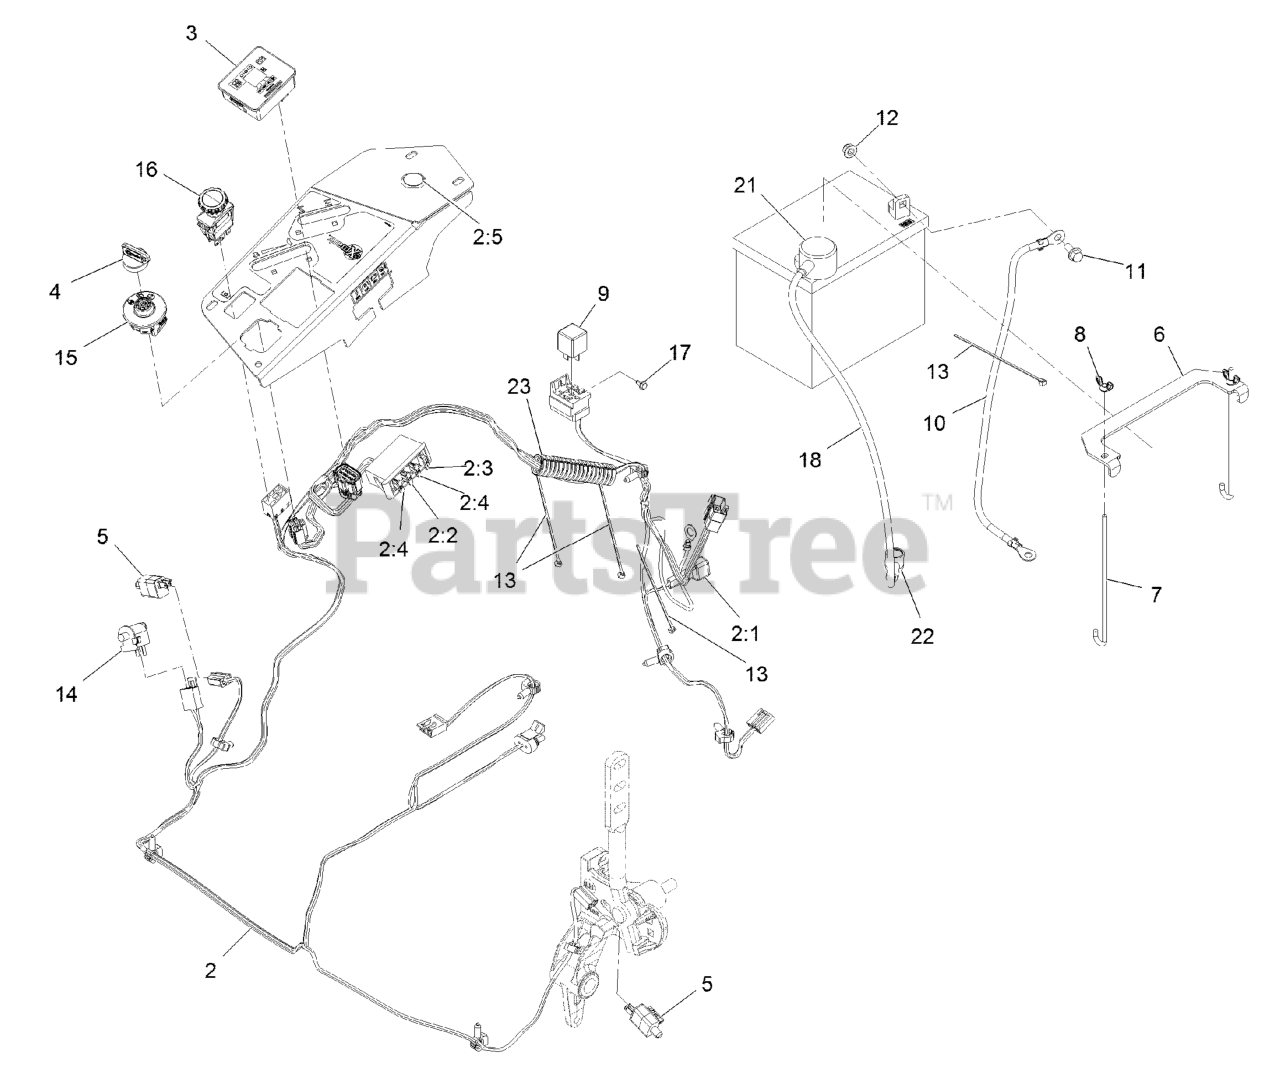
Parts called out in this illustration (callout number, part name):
2	HARNESS-WIRE, MAIN
2:2	FUSE-BLADE, 10 AMP
2:3	FUSE-BLADE, 15 AMP
2:4	FUSE-BLADE, 25 AMP
2:5	CAP-PLUG
3	FUEL/HOUR METER ASM
4	KEYS-IGNITION (SPARE PAIR
4	KEY-IGNITION
6	STRAP-TIE DOWN, BATTERY
7	BOLT-HOLDDOWN
8	WINGNUT
10	CABLE-BATTERY, NEGATIVE
11	SCREW-HHF
12	NUT-HF, NI
13	TIE-CABLE
14	SWITCH-BAIL
15	SWITCH-IGNITION
16	SWITCH-PTO, 10 AMP
17	SCREW-HWH
18	CABLE-BATTERY, POSITIVE
21	INSULATOR-BATTERY
22	INSULATOR-SOLENOID
23	COVER-HOSE
